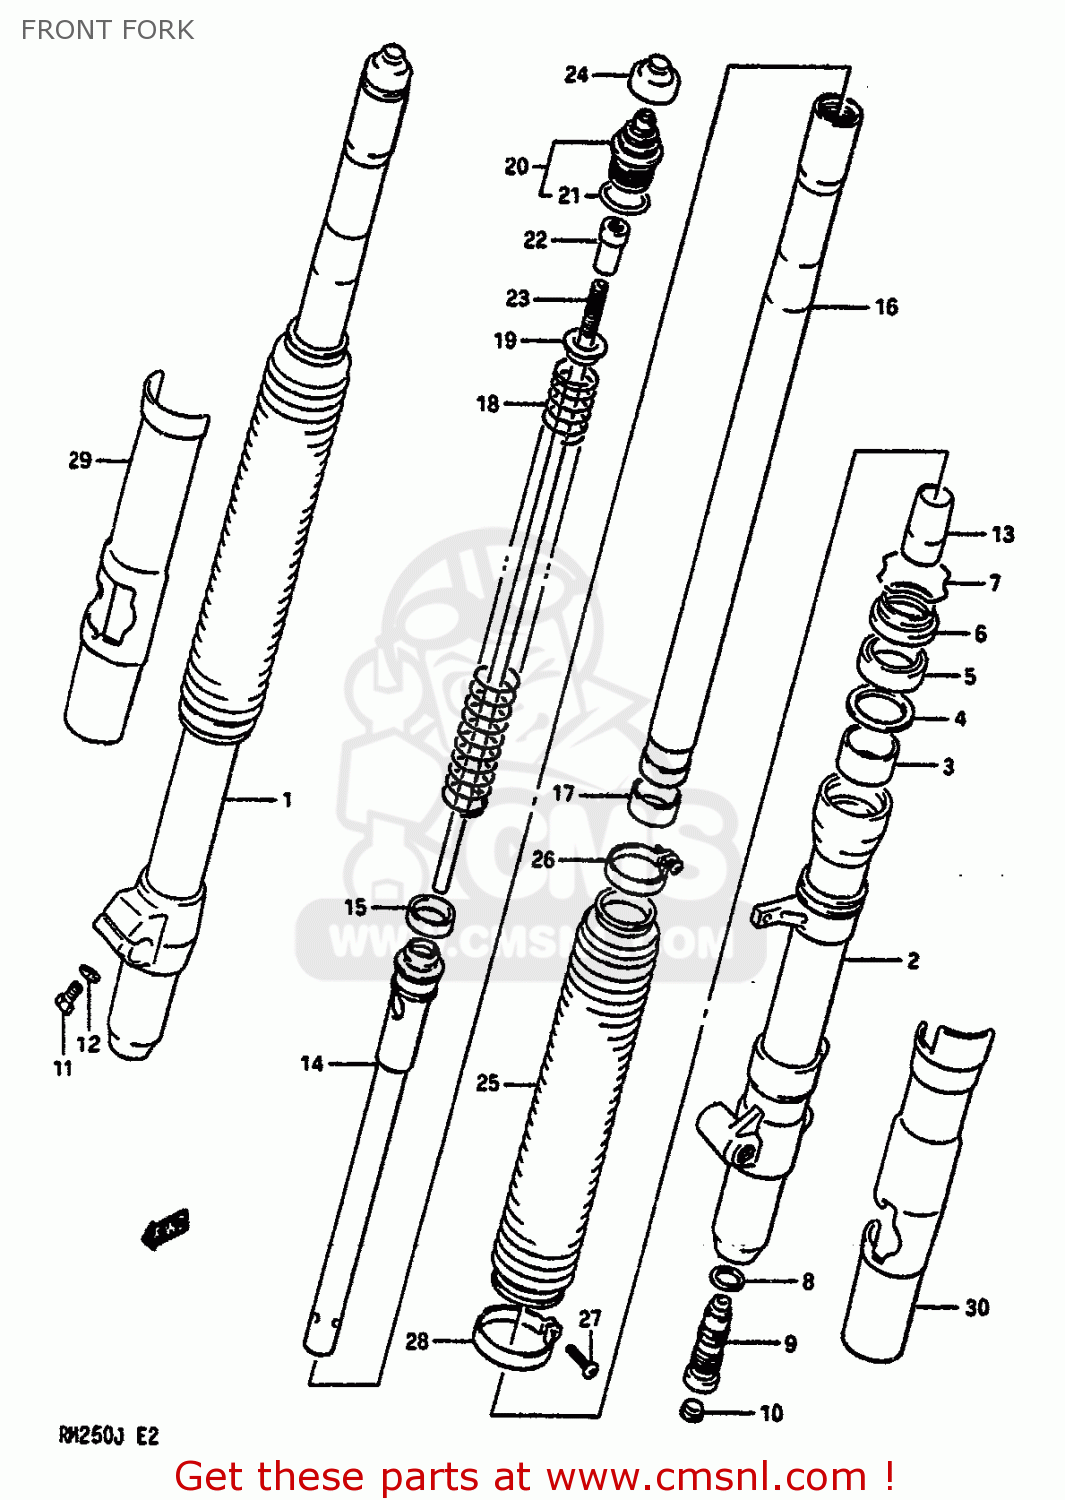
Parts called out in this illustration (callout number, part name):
1	TUBE,OUTER,RIGHT
2	TUBE,OUTER,LEFT
3	METAL,SLIDE
4	WASHER
5	OIL SEAL,FRONT FORK
6	DUST SEAL,FRONT FORK
7	RING,STOPPER
8	GASKET (NAS)
9	VALVE ASSEMBLY
10	CAP,FRONT FORK DF
11	BOLT
12	LOCK WASHER
13	PIECE,OIL LOCK
14	CYLINDER,FRONT FORK
15	RING,FRONT FORK PISTON
16	TUBE,FORK,INNER
17	PISTON
18	SPRING
19	GUIDE,FRONT FORK SPRING
20	CAP
21	O RING
22	NUT,PISTON ROD
23	ROD,PISTON
24	CAP
25	BOOT
26	BAND,BOOT,UPPER
27	SCREW,BAND BOOT(3.5X10)
28	BAND,BOOT LWR
29	PROTECTOR,RIGHT
30	PROTECTOR,LEFT
